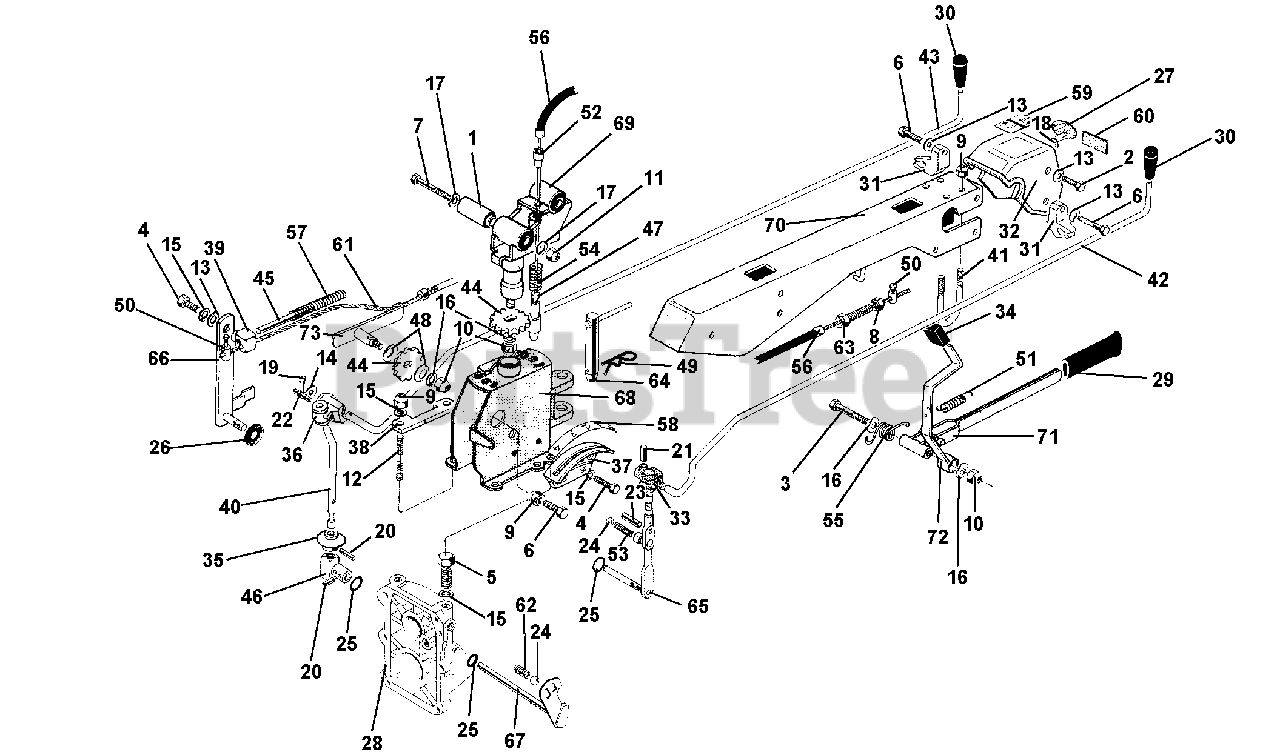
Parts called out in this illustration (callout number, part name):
1	SILENTBLOCK
2	SCREW M8 X 16
3	SCREW TE M10 X 90
4	SCREW M8 X 12
5	SCREW M8 X 20
6	SCREW M8 X 35
7	SCREW TE M12 X 95 5739 8G
9	NUT, SELF LOCKING M8
10	NUT, SELF LOCKING M10 LOW
11	NUT, SELF LOCKING M12 LOW
12	STUD M8 X 38 X 14 X 20
13	WASHER, FLAT 8.4
14	WASHER P10.5 X 18
15	WASHER, LOCK 8.4
16	WASHER, LOCK 10.5
17	WASHER, LOCK 13
18	WASHER, LOCK FOR PINS
20	LOCKING PIN 4 X 20 SPIRAL
21	PIN, LOCKING SW 3 X 22 SPIRAL
22	LOCKING PIN 4 X 24 SPIRAL
23	LOCKING PIN SPIRAL
24	BALL 15/32 RIV RB-11.906
25	O-RING 115 11.91 X 2.62
26	SEAL, OIL 12 X 19 X 5 STANDARD
31	SUPPORT CONTROL ROD CUT
32	STEERING COLUMN INSTRUM. PANEL
33	GEARBOX ARTICULATION
34	KNOB REDUCTION UNIT LEVER
35	P.T.O. STOP RING
36	P.T.O. ARTICULATION
37	GEARBOX SELECTOR
38	REVERSE SPEED LEVER DOG
39	REVERSER BLOCK
40	PTO CONTROL LEVER
41	HANDLEBAR U-BOLT
42	GEARBOX CONTROL ROD
43	PTO CONTROL ROD
44	REVERSE GEAR
46	P.T.O. JOINT
47	STEERING COLUMN PIN
48	PROTECTION END D 32
50	CLAMP, CABLE
51	LEVER RETURN SPRING
52	END, SHEATH
54	STEERING COLUMN RELEASE SPRING
55	HANDLEBAR RELEASE SPRING
56	WIRE AND SHEATH L 90
57	REVERSER SPRING
58	SPEED STICKER
59	DECAL FOR STEERING COLUMN
61	WIRE SHEATH L-1280 CLUTCH/BR.
62	P.T.O. SPRING
63	ADJUSTING SCREW
65	GEARBOX LEVER
66	REVERSER LEVER
68	STEERING COLUMN SUPPORT
69	STEERING COLUMN COUPLING
70	STEERING COLUMN
71	HANDLEBAR RELEASE LEVER
72	STEERING COLUMN LOCKING LEVER
73	REVERSER POSITION LEVER
